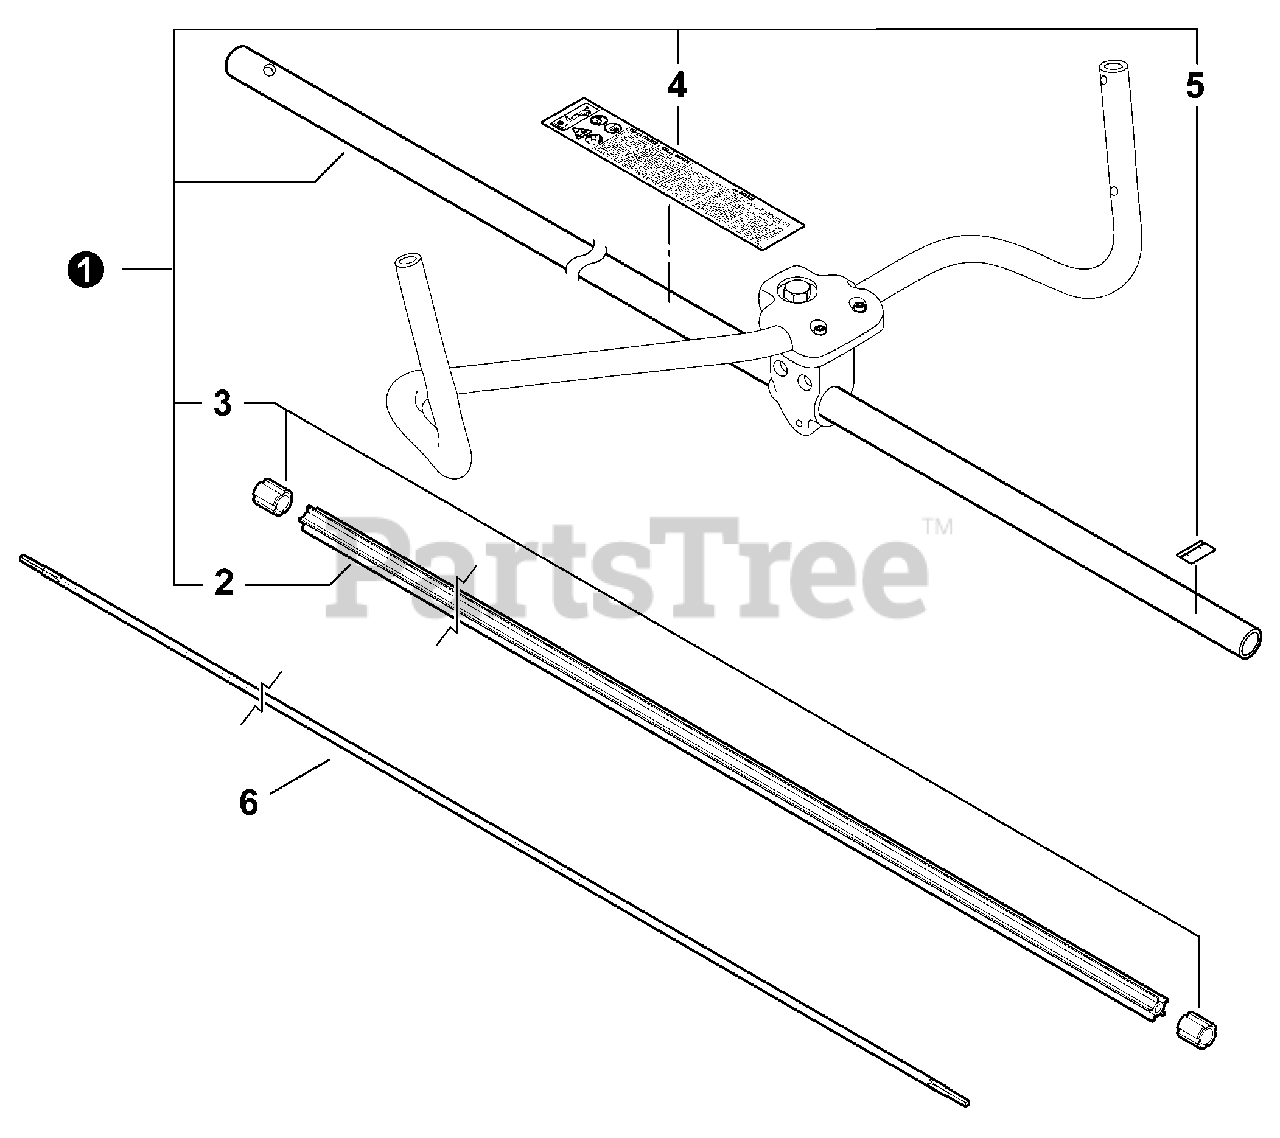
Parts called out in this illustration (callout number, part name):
1	MAIN PIPE ASY
2	LINER - FLEXIBLE
4	LABEL - CAUTION
5	LABEL - ALIGNMENT
6	DRIVESHAFT - FLEXIBLE
